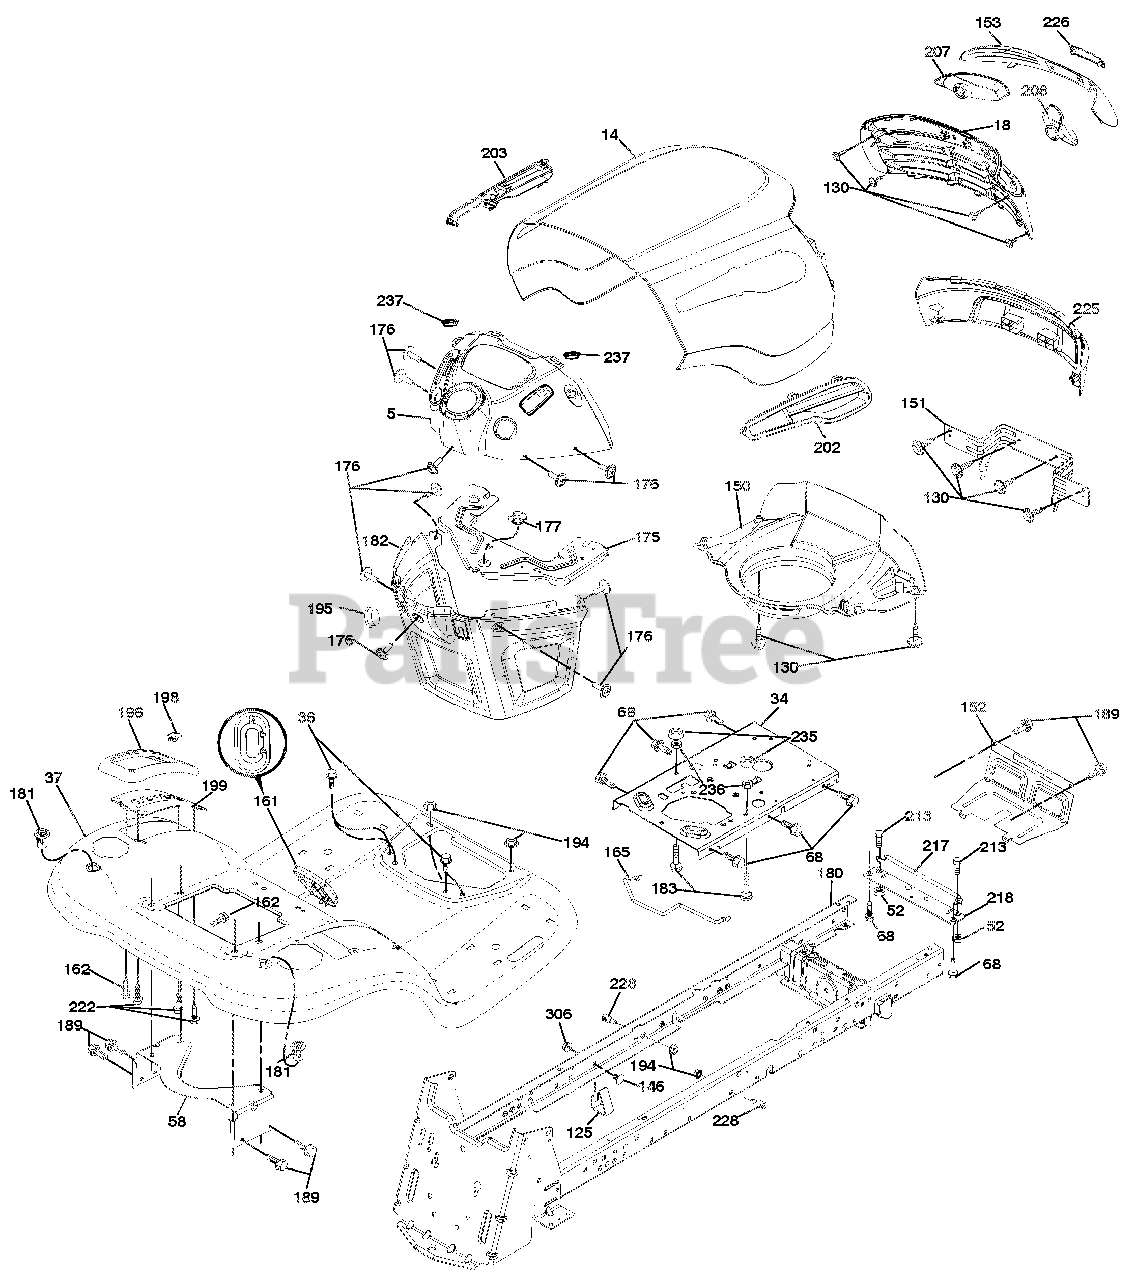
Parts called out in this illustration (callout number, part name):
5	DASH P/L TEX CABLE
18	GRILLE.ELITE.ARIENS.BLACK
34	PLATE.ENGINE.WELDED.CHASSIS
36	SCREW.5/16-18X3/4.SMGML.TAP/R
52	Nut, Hex, Crownlock 5/16-18
58	FENDER SUPPORT BRACKET
68	SCREW.THDROL.5/16-18 X 1/2TYTT
125	CLIP.FUEL.LINE
150	AIR DUCT
151	BRACKET.PIVOT
152	SHIELD.BROWNING.W/TEX
153	LENS.BAR
161	CONSOLE FUEL WINDOW
162	SCREW.HEX.WSH.HI-LO.1/4X1/2UNC
165	SUPPORT.TANK.REAR.W/TEX
175	CROSSMEMBER LT
176	SCREW.#10-24X5/8.RND.QUDRX.GIM
177	BUSHING.STEERING.YT/GT
180	CHASSIS
181	BUSHING MNT FEND CRGO BLK TEX
182	DASH.LOWER.LT.CCS
183	BOLT.FIN.HEX.5/16-18 UNC X1-1/
189	SCREW.5/16-18X3/4.SMGML.TAP/BL
194	Nut, Lock Hex Flange 5/16-18 u
195	PLUG HOLE DASH TOWER
196	CONSOLE ASM. DECK LIFT
198	INDICATOR DECK LIFT
199	PLATE DECK LIFT
202	VENT RH
203	VENT.SIDE.LH
207	BEZEL.LH
208	BEZEL.RH
213	BOLT.HEX.HD.1/4-20UNC X 3/4
217	ROD.PIVOT.HOOD
218	X-PIECE.HOOD.STOP.NON/STEALTH
222	SCREW.THD.ROLL.1/4-20 X 5/8
226	ARIENS.LOGO.PLATE
228	STUD.FASTNER.W/'D'ANTI-ROTATIO
235	SPACER.FENDER
236	NUT.CENTER LOCK.5/16-18 UNC
237	PLUG.MOUNT.CARGO
306	Nut, Hex, Flangelock 3/8-16
